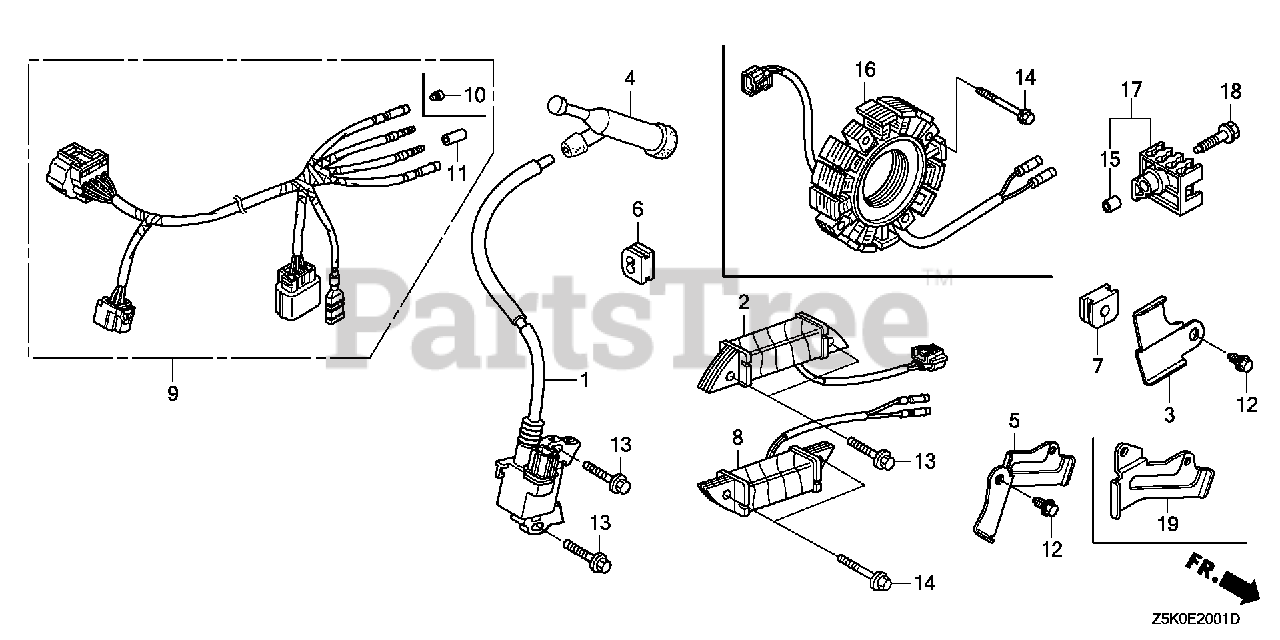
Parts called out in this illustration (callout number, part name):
1	COIL ASSY., IGNITION
2	COIL ASSY., POWER
3	BRACKET B, HARNESS
4	CAP ASSY., NOISE SUPPRESSOR (NGK Y-EZD)
6	GROMMET, WIRE
7	GROMMET, WIRE
9	WIRE HARNESS ASSY., ENGINE
10	PLUG, CONNECTOR (INNER)
11	PLUG, CONNECTOR (OUTER)
12	BOLT, FLANGE (6X12) (CT200)
13	BOLT, FLANGE (6X28) (CT200)
